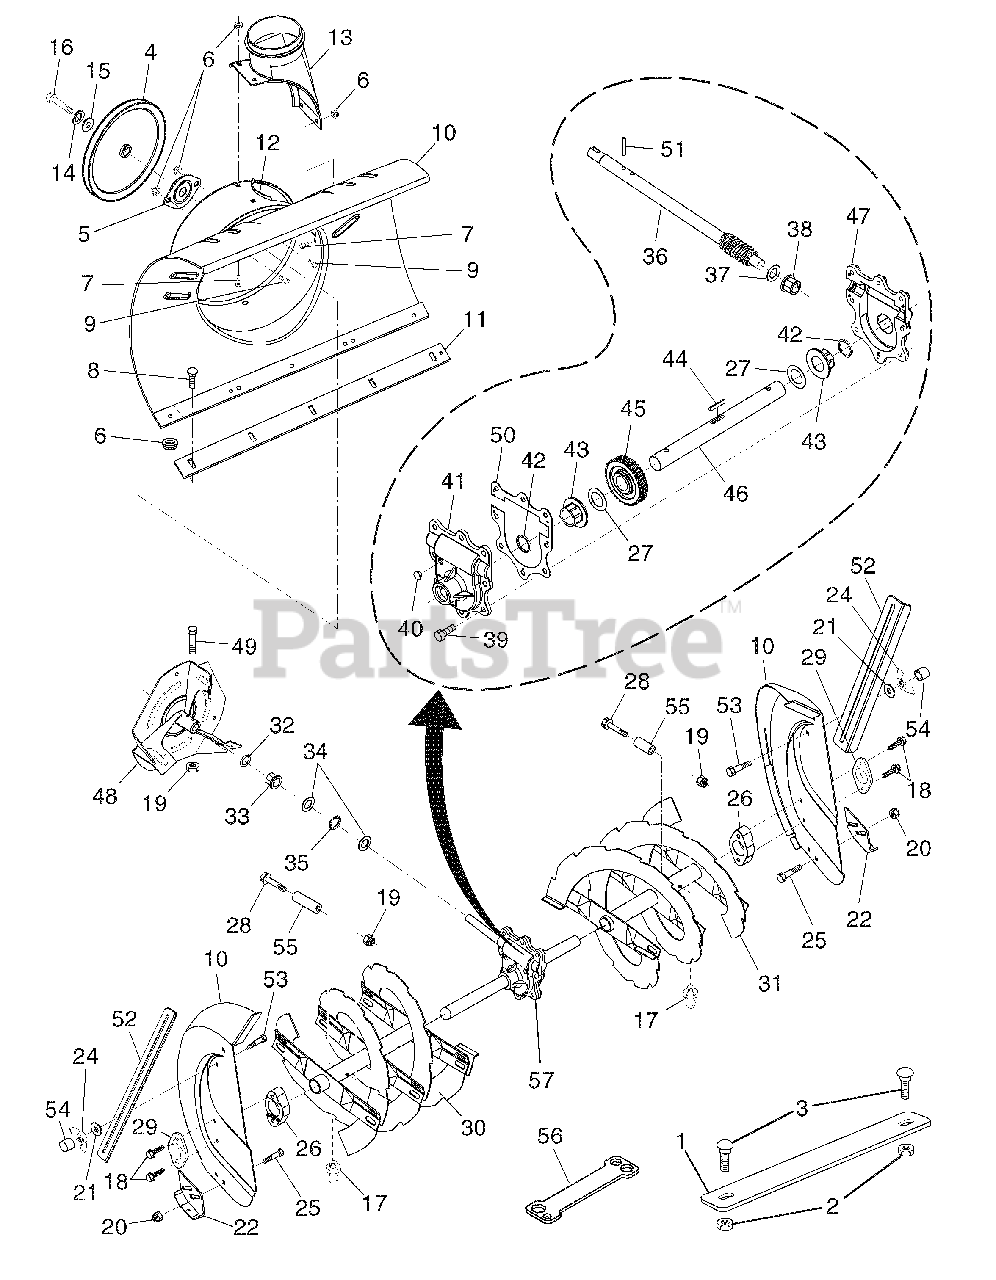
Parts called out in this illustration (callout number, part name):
1	Bar, Weight
2	Nut, Hex 5/16-18
3	Bolt, Carriage 5/16-18 x 1-1/4
4	Pulley, Impeller
5	Bearing Assembly, Flange
6	Nut, Hex Flange 5/16-18
7	Bolt, Flat Head, Carriage 5/16-1 8 x 5/8
8	Bolt, Carriage 5/16-1 8 x 5/8
10	Housing, Auger
11	Bar, Scraper
12	Bracket, Corner Discharge
13	Base, Discharge Chute
14	Washer, Lock 5/16
15	Washer, Flat
16	Screw, Hex Head 5/16-18 x 1.00
17	Grease Fitting
18	Screw, Hex Head 5/16 x 1
19	Nut, Hex Lock 1/4-20
20	Nut, Hex Lock 5/16-18
21	Washer, Flat 5/16
22	Skid Plate, Heavy Duty
25	Bolt, Shoulder 1/4-20
26	Bearing Retainer, Plastic
27	Washer, Thrust, 1"
28	Screw
30	Auger Assembly, RH
31	Auger Assembly, LH
33	Bushing, Flange 3/4
34	Washer, Thrust 3/4
35	Bearing, Thrust 3/4
36	Shaft, Impeller
37	Washer, Thrust 5/8
38	Bushing, Flange 5/8
39	Screw, Hex Head 5/16-18 x 3/4
40	Plug, Case
41	Housing, Gearbox, RH
42	Seal, Oil
43	Bushing, Flange, 1"
44	Key, Square 1/4 x 1/4 x 7/8
45	Gear, Worm
46	Shaft, Auger
47	Housing, Gearbox, LH
48	Impeller Assembly
49	Screw, Hex Head 1/4-20 x 1-5/8
50	Gasket, Gearbox
51	Pin, Roll 3/16 x 1-1/8
52	Bar, Drift
53	Bolt, Hex Head
56	Multi-Wrench
57	Gearbox Assembly
